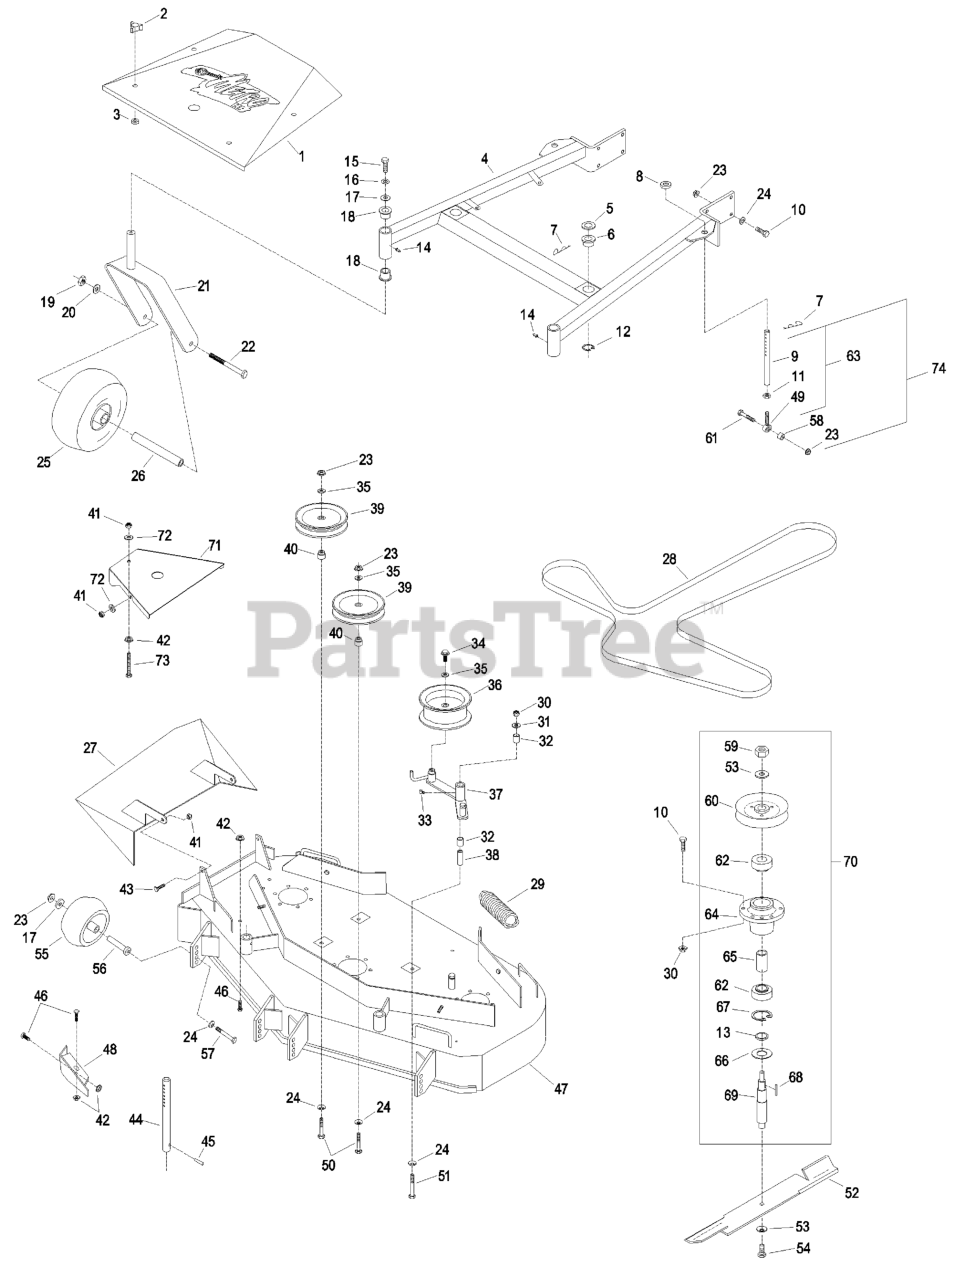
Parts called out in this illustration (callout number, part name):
1	SHIELD W/DECAL,MHP48
2	KNOB-3 PRONG
4	DECK SUPPORT W/BSHGS 48"
5	SPACER-DECK SUPPORT
6	BUSHING-DECK
7	PIN,HAIR COTTER
9	LINK,SUPPORT
13	SPACER-PULLEY/BEARING
18	BEARING-FLANGED
28	BELT - V, B
32	SLEEVE-BEARING
38	BUSHING-PIVOT, IDLER
39	PULLEY-IDLER
40	BUSHING-IDLER
44	ROD,DECK SUPPORT
47	ASM,DECK W/DECALS TTHP/MH
49	BALLJOINT
51	SCREW-HH
53	WASHER-SPRING
55	ROLLER-SCALP, ANTI
56	BUSHING-ROLLER
60	SHEAVE,W/HUB 5.72
62	BEARING
65	SPACER-BEARING
66	GUARD-BEARING, BOTTOM
68	KEY-RECTANGLE
69	SHAFT,SPINDLE
70	HOUSING,CUTTER COMPLETE
73	BOLT,TAP HH
